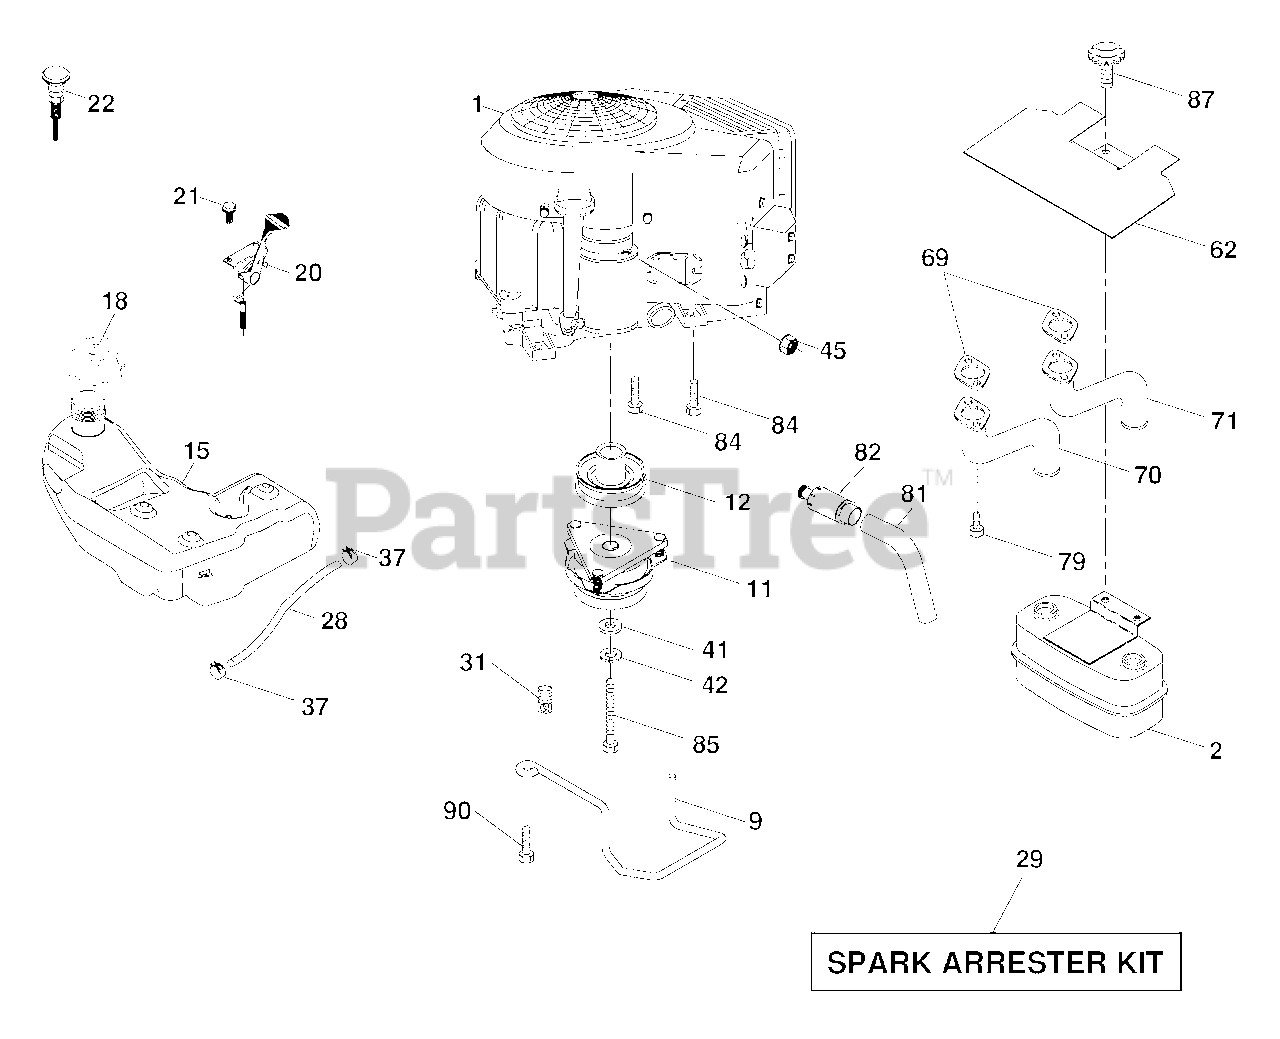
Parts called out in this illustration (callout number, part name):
2	Muffler
9	Keeper Asm. Belt Engine
11	Clutch Electric
12	Pulley Engine
15	Tank Fuel 4.0
18	Cap Asm
20	Control Throttle
21	Screw 10 x 3/4 Single Lead-Hex
22	Control Choke
28	Fuel Line
29	Spark Arrester Kit
31	Clip Push-In Hinged
37	Clamp Hose
41	Washer 1-1/2 OD x 15/32 ID x .250
42	Washer Lock 7/16
45	Nut Keps Hex 1/4-20 unc
62	Shield Heat Muffler
69	Gasket
70	Tube Exhaust LH
71	Tube Exhaust RH
79	Screw Socket Head
81	Tube Drain Oil Easy
82	Plug Drain Oil
84	Screw 3/8-16 x 1-1/2
85	Bolt Hex 7/16-20 x 3.75 Gr. 5
87	Bolt 5/16-18 unc x 1 w/Sems
90	Screw 3/8-16 x 1
